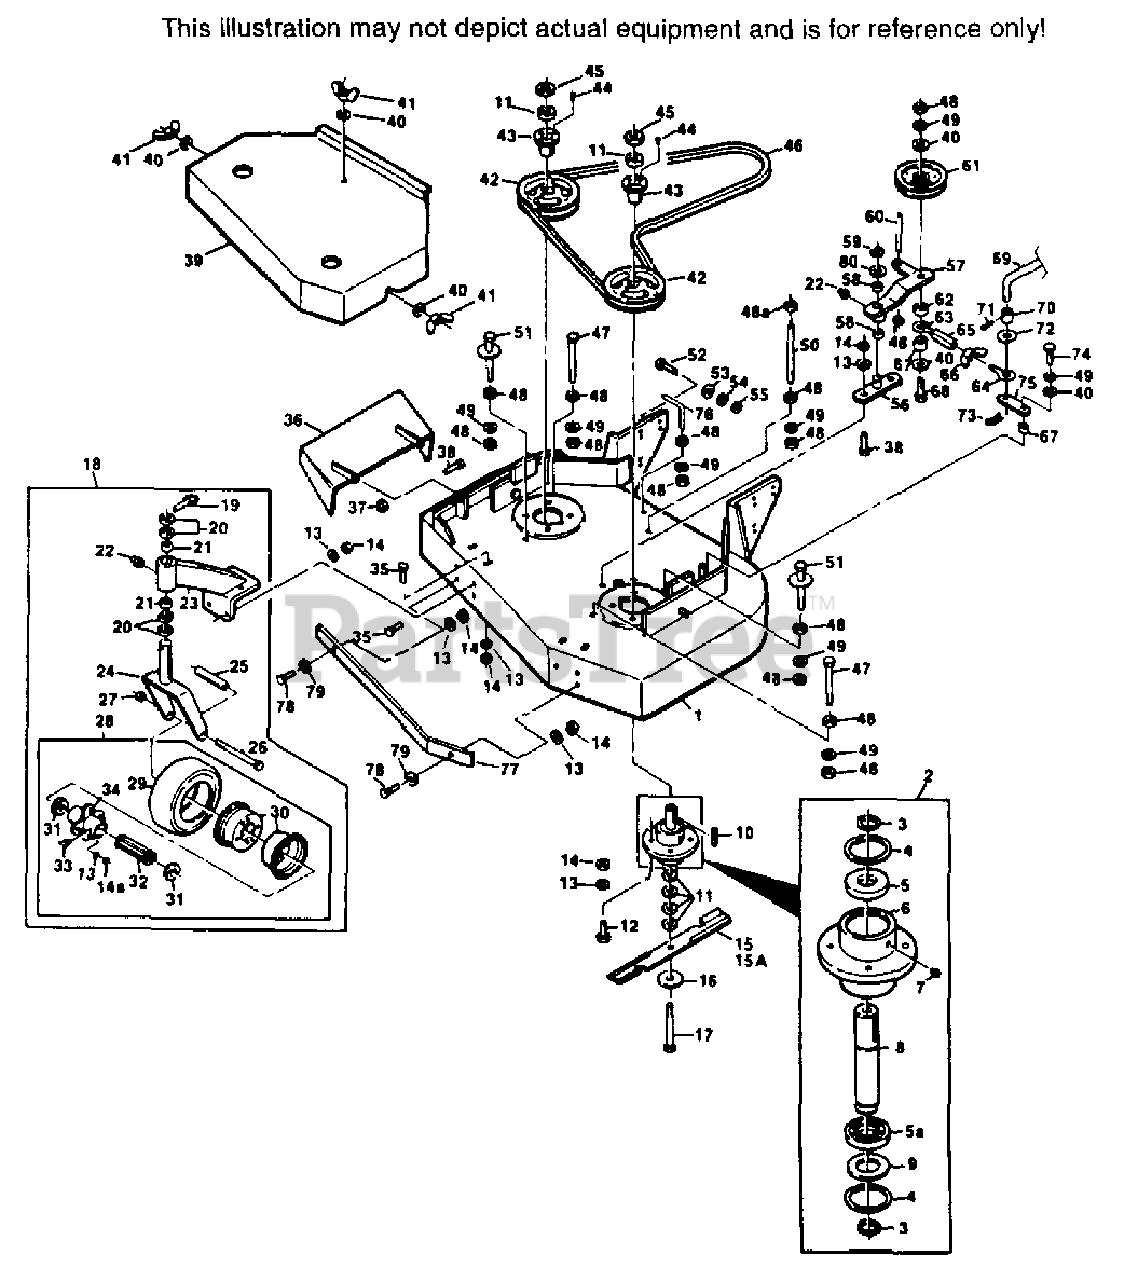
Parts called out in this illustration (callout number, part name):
1	CUTTER DECK WLD
2	CUTTER SPINDLE ASSY.(INCL 3-9)
3	RETAINING RING, 1" EXT.-INVERTED
4	RETAINING RING, 2-7/16 INT. BSC
5	BEARING, UPPER
5A	BEARING, LOWER
6	SPINDLE HOUSING
7	GREASE FITTING, STR 5/16 SERR
8	SPINDLE, CUTTER BLADE
9	WASHER, 1-5/16 X 2-7/16 X 16GA
10	KEY, 1/4 X 1/4 X 2
11	SPACER, CUTTER BLADE
15	CUTTER BLADE 16 1/2"
15A	CUTTER BLADE 16 1/2" HI LIFT
16	FLAT WASHER, 5/8 W
17	HEX HD BOLT, 5/8-11 X 9-1/2
18	CASTER ASSY.(INCL. 19-28)
19	QUICK PIN
20	SPACER, CASTER YOKE, 1/2" LONG
21	BRONZE BEARING
22	GREASE FITTING, STR. 1/4-28
23	SUPPORT ASSY.
24	CASTER YOKE WLD
25	SLEEVE, CASTER WHEEL BRG.
26	HEX HD BOLT, 1/2-13 X 5-1/2
28	WHEEL ASSY,(INCL. 13-14A, 29-34)
29	TIRE ONLY CASTER WHEEL
30	RIM PAIR, CASTER WHEEL
31	RETAINER, BEARING, CASTER WHEEL
32	ROLLER BEARING, CASTER WHEEL
33	GREASE FITTING, 45' 1/4-28
34	HUB ASSY, INCL.
36	DISCHARGE CHUTE WLD
37	HEX NUT, 5/16-18 ELASTIC STOP
39	BELT COVER ASSY(INCL. DECAL)
40	WASHER, 25/64 X 15/16 X 12 GA.
40A	WASHER, 13/32 X 13/16 X 16 GA.
41	WING NUT, 3/8-16 ELASTIC STOP
42	PULLEY(INCL. 43-44)
43	TAPERED HUB
46	BELT, BLADE DRIVE
48A	HEX NUT, 3/8-16 CTR LOCKNUT
50	SUPPORT, BELT COVER
51	BELT GUIDE WLD
53	WASHER, 15/32 X 59/64 X 16 GA.
55	HEX NUT, 7/16-14 ELASTIC STOP
56	IDLER PIVOT
57	IDLER ARM ASSY.(INCL. 22&58)
58	BRONZE BEARING
59	RETAINING RING, 3/4 EXT,-"E"
61	IDLER PULLEY, BELT CLUTCH
62	SPACER, IDLER
63	EYEBOLT, LH
64	EYEBOLT, RH
65	TURNBUCKLE
66	WING NUT, 5/16-18
67	SLEEVE, CLUTCH ROD
69	BLADE CLUTCH ROD, LOWER
70	SLEEVE, CLUTCH ROD
72	WASHER, 33/64 X 1 X 16 GA.
73	HAIR PIN, LARGE
75	CAM LINK
76	BELT GUIDE
77	BUMPER BALLAST
79	FLAT WASHER 11/32 X 11/16 X 16 GA
80	WASHER, 3/4 X 1 1/4 X .035
